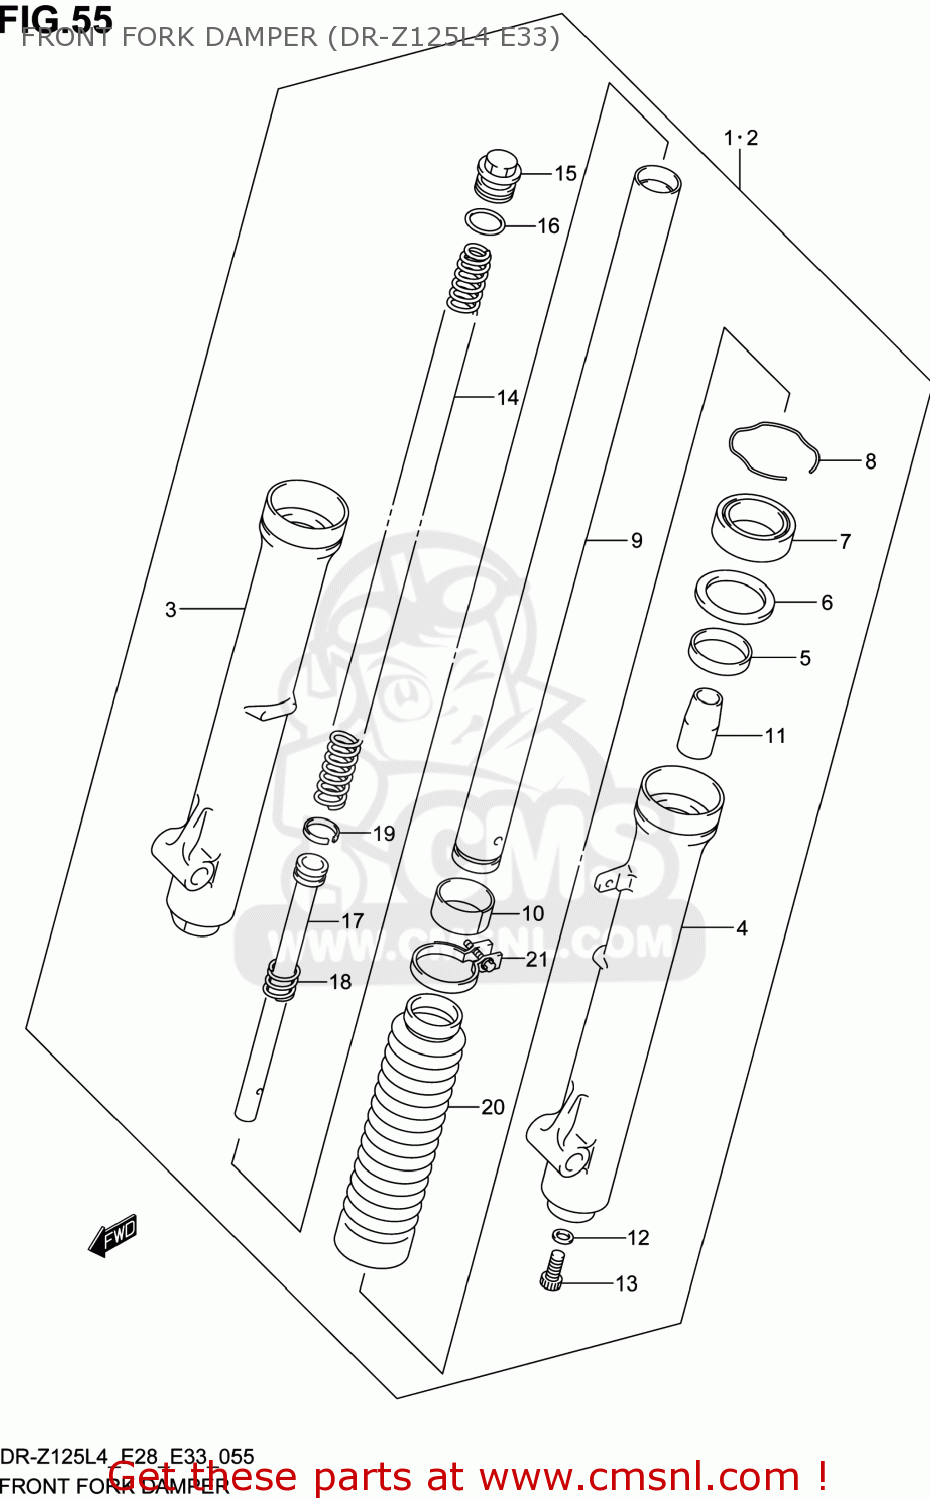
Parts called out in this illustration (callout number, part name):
1	DAMPER ASSY,FR FORK,R
2	DAMPER ASSY,FR FORK,L
3	TUBE,OUTER,R
4	TUBE,OUTER,L
5	BUSH,GUIDE
6	SPACER,SEAL
7	SEAL,OIL
8	SEAL,OIL STOPPER RING
9	TUBE,INNER
10	BUSH,SLIDE
11	PIECE,OIL LOCK
12	GASKET (NAS)
13	BOLT(8X27)
14	SPRING,FR
15	BOLT
16	O RING
17	CYLINDER
18	SPRING,REBOUND
19	RING
20	BOOT
21	BAND
